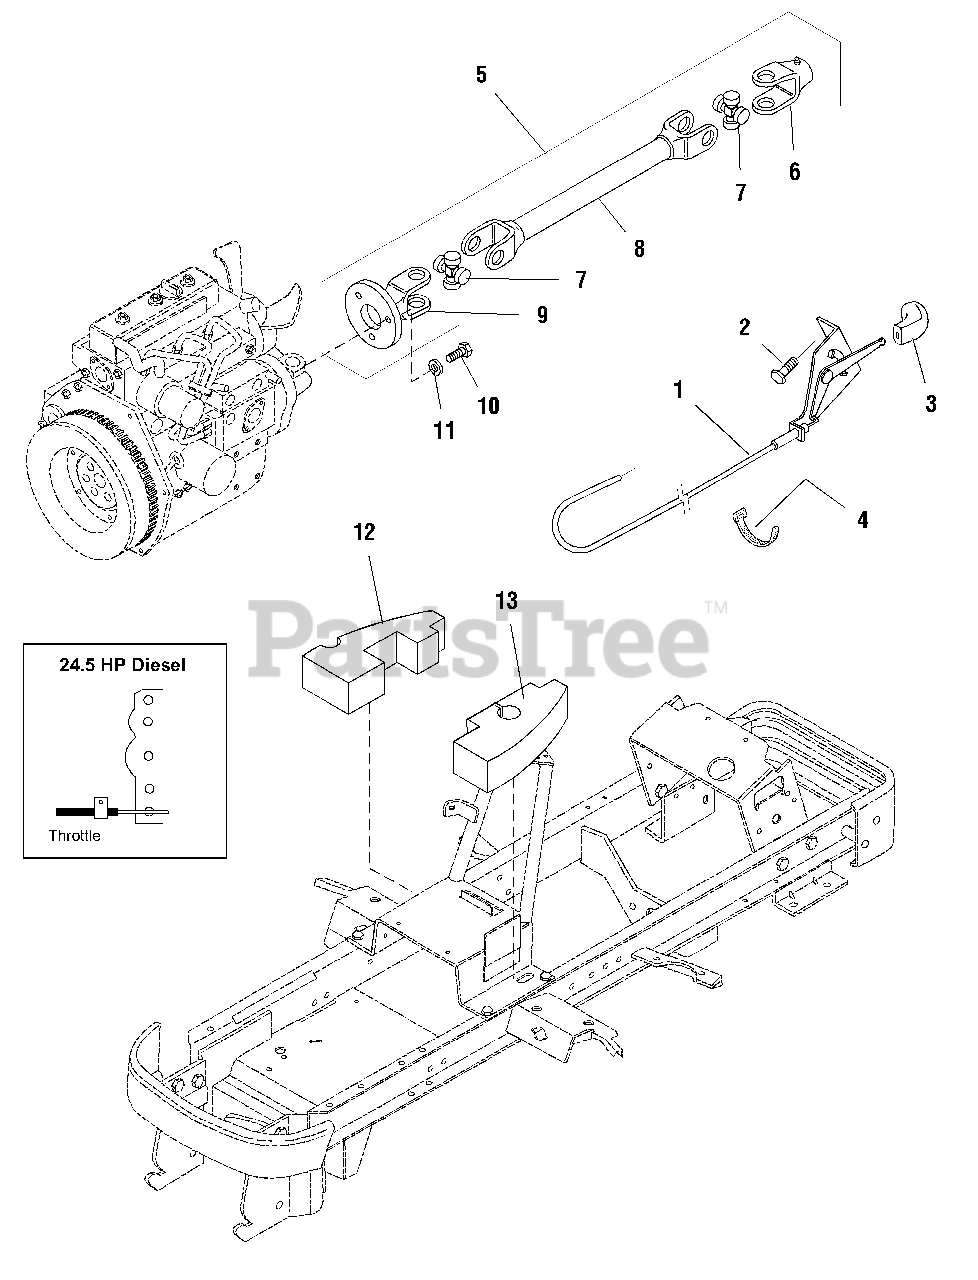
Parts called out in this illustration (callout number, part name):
1	CONTROL, Throttle
2	CAPSCREW, #12-24 x 5/16
3	KNOB, Throttle
5	DRIVE SHAFT
7	CROSS & BEARING KIT
8	YOKE & TUBE ASSEMBLY
9	YOKE, Flange
10	CAPSCREW, Socket Head, M8-1.25 x 20
11	LOCKWASHER, External Tooth
